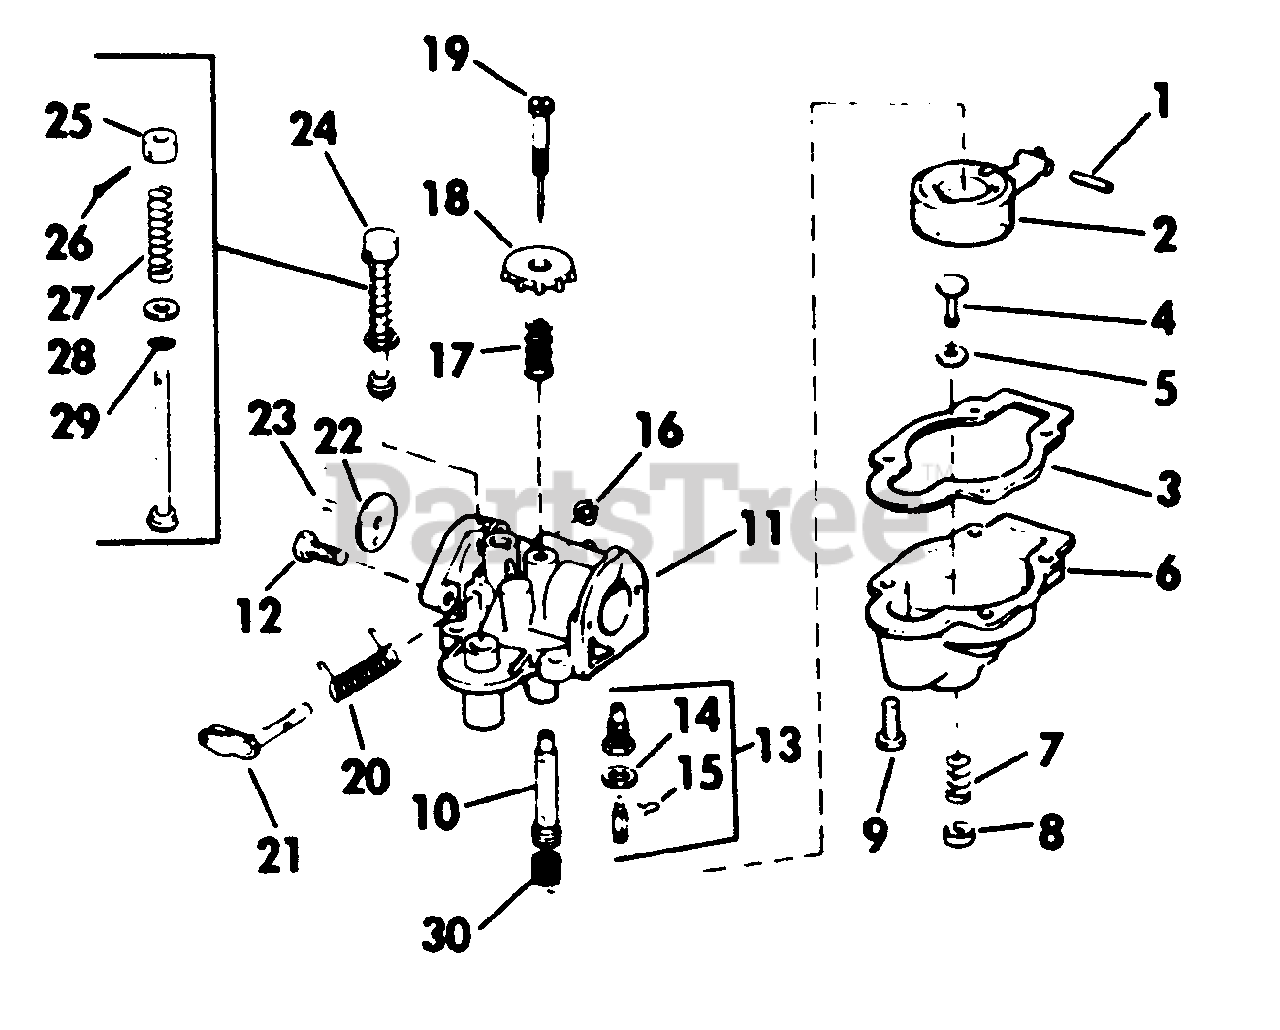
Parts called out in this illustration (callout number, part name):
1	Pin-Float Arm Hinge
2	Float and Arm Assy.
3	Gasket-Float Chamber
4	Valve Stem
5	Valve Seat
6	Chamber-Float
7	Valve Spring
8	Valve Keeper
9	Screw-Float Chamber
10	Nozzle
11	Carburetor Body Assy.
13	Float Valve & Seat
14	Washer-Float Valve Seat
15	Clip
16	Grip Ring
17	Spring-Needle Adj.
18	Knob-Needle Adj.
19	Needle Assy.
20	Spring-Throttle
21	Throttle Shaft & Lever Assy.
22	Disc-Throttle
23	Screw-Throttle Shaft Disc
24	Primer Assy.
25	Knob Primer
26	Cotter Pin
27	Spring Compression
28	Washer-Plain
29	"O" Ring
